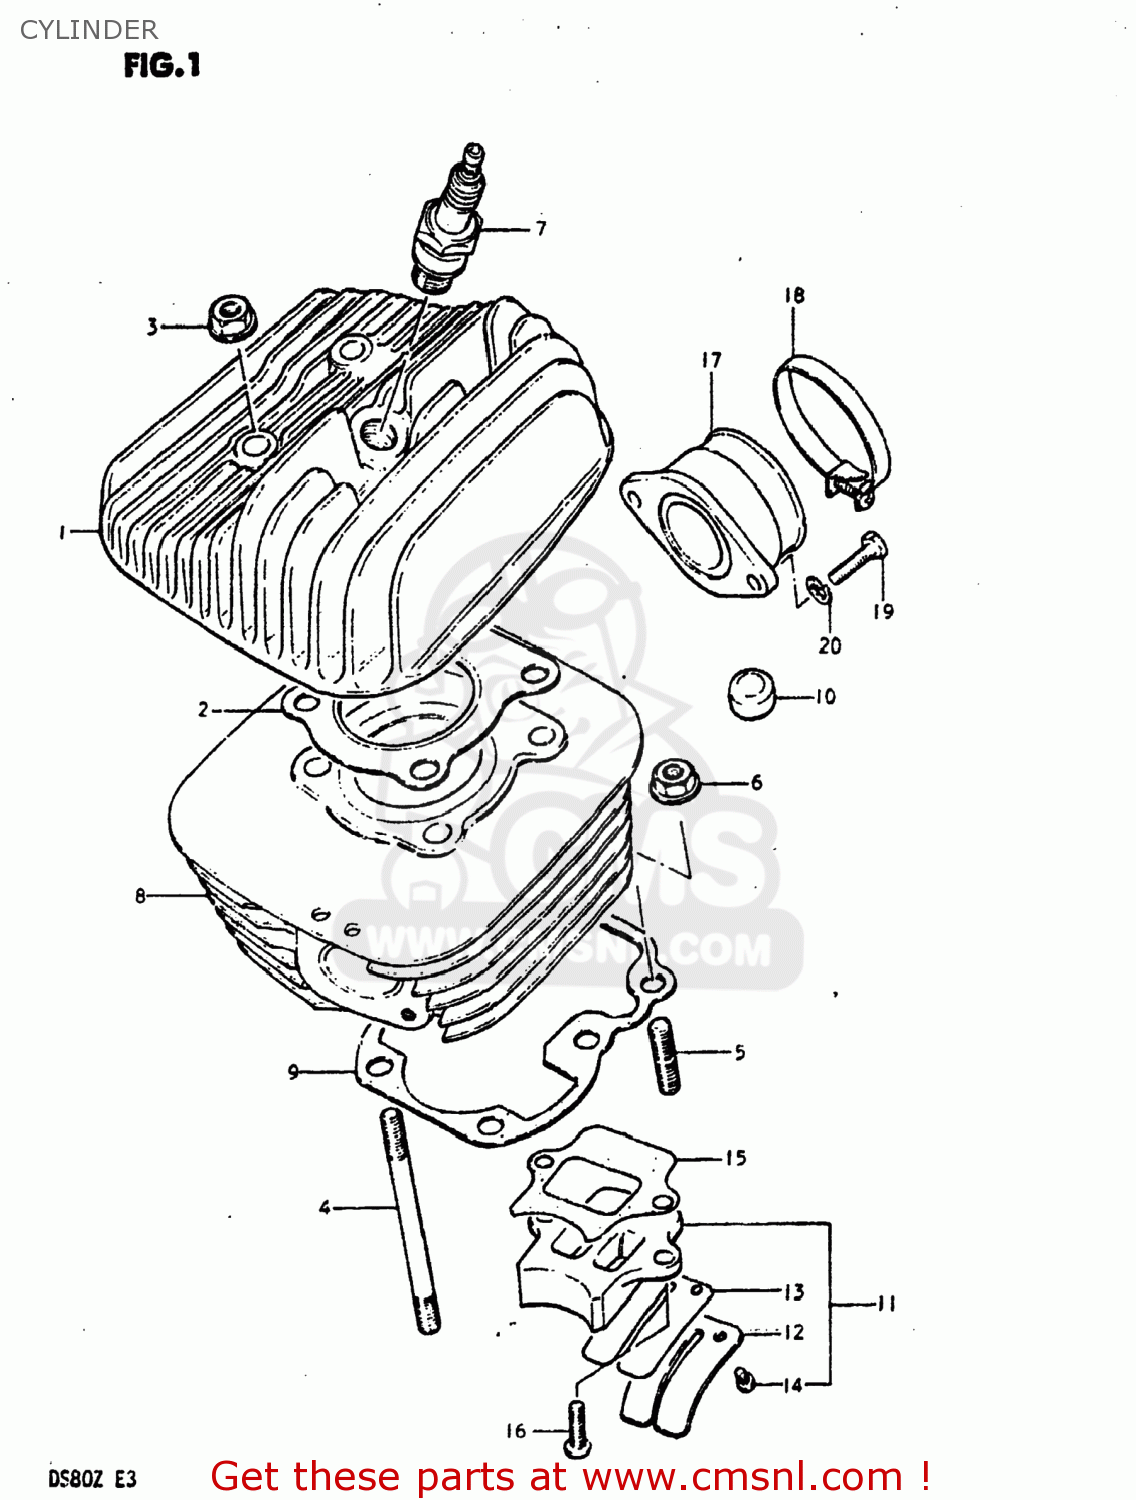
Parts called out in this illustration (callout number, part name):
1	HEAD,CYLINDER
2	GASKET,CYLINDER HEAD (NAS)
3	NUT
4	BOLT,STUD
5	STUD 6X20
6	NUT
7	SPARK PLUG B7ES
8	CYLINDER
9	GASKET,CYLINDER (NAS)
10	PAD,CYLINDER
11	VALVE ASSY,REED
12	STOPPER,REED VALVE
13	VALVE,REED
14	SCREW,REED VALVE
15	GASKET,REED VALVE (MCA)
16	SCREW
17	PIPE,INTAKE
18	CLAMP
19	BOLT
20	LOCK WASHER
